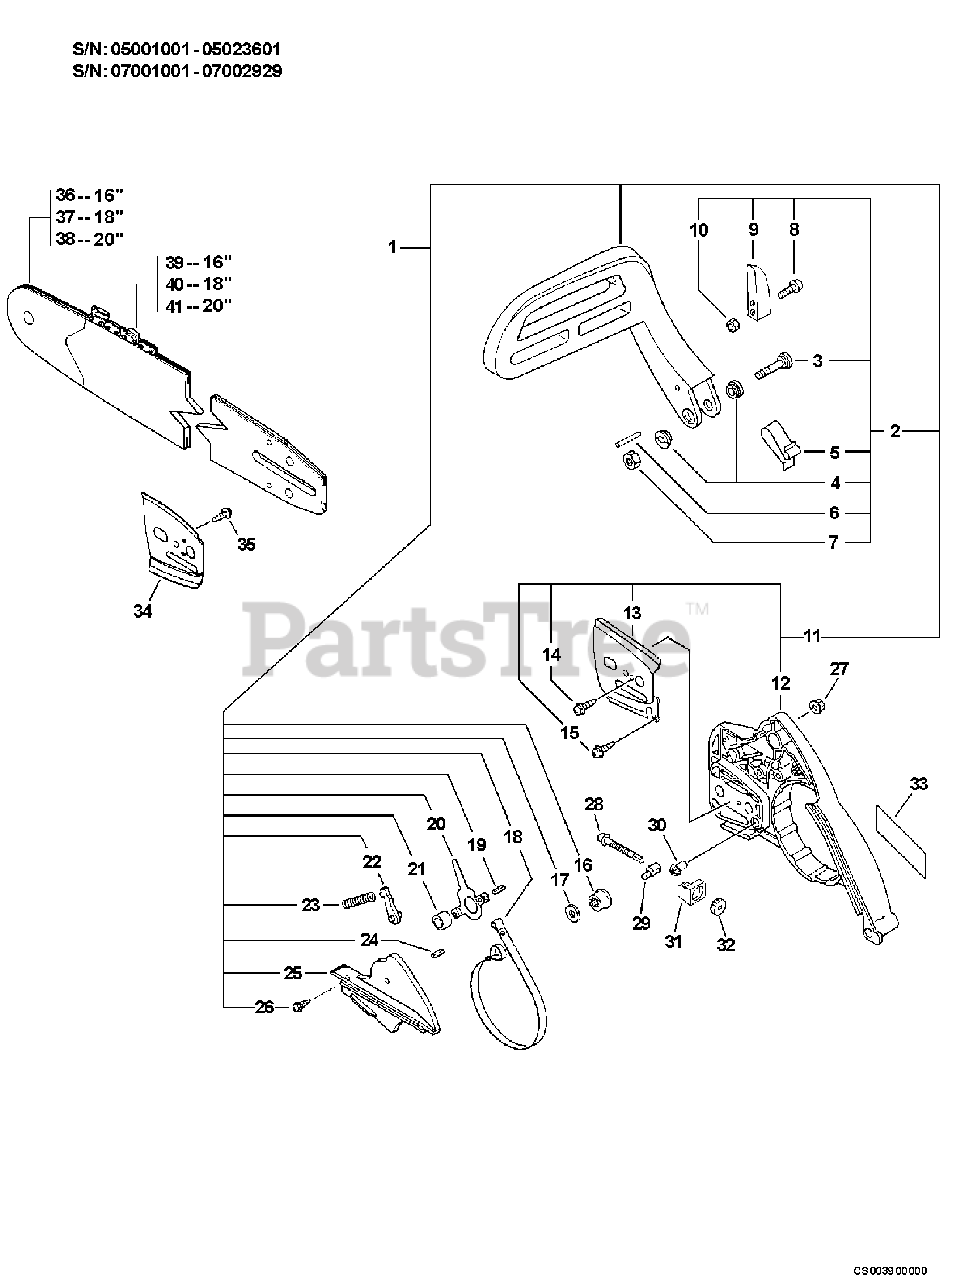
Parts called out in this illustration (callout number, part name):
1	CHAIN BRAKE ASSY
2	BRAKE LEVER ASSY
3	SCREW - 5X32
6	PIN - 3X26
7	LOCKNUT - 5
8	SCREW - 4X18
9	WEIGHT, BRAKE
11	SPROCKET GUARD ASSY
12	GUARD, SPROCKET
13	PLATE, GUIDE - OUTER
14	SCREW - 3X6
15	SCREW - 4X10
16	ADJUSTER, BRAKE BAND
17	WASHER - 8
18	BAND, BRAKE
19	PIN - SPRING -- 4X8
20	LEVER, BRAKE
21	WASHER - 5
22	STOPPER, BRAKE
23	SPRING, BRAKE
24	PIN - SPRING -- 2.5X12
25	COVER, BRAKE
26	SCREW - 4X10
27	NUT - FLANGE
28	SCREW, TENSIONER
29	TENSIONER, CHAIN
30	GEAR - PINION
31	COLLAR - 8
32	GEAR - BEVEL
33	LABEL - ECHO
34	PLATE, GUIDE - INNER
35	SCREW - 4X6
36	GUIDE BAR - 16" (40cm)
37	GUIDE BAR - 18" (45cm)
38	GUIDE BAR - 20" (50cm)
39	SAW CHAIN - 16" (40cm)
40	SAW CHAIN - 18" (45cm)
41	SAW CHAIN - 20" (50cm)
